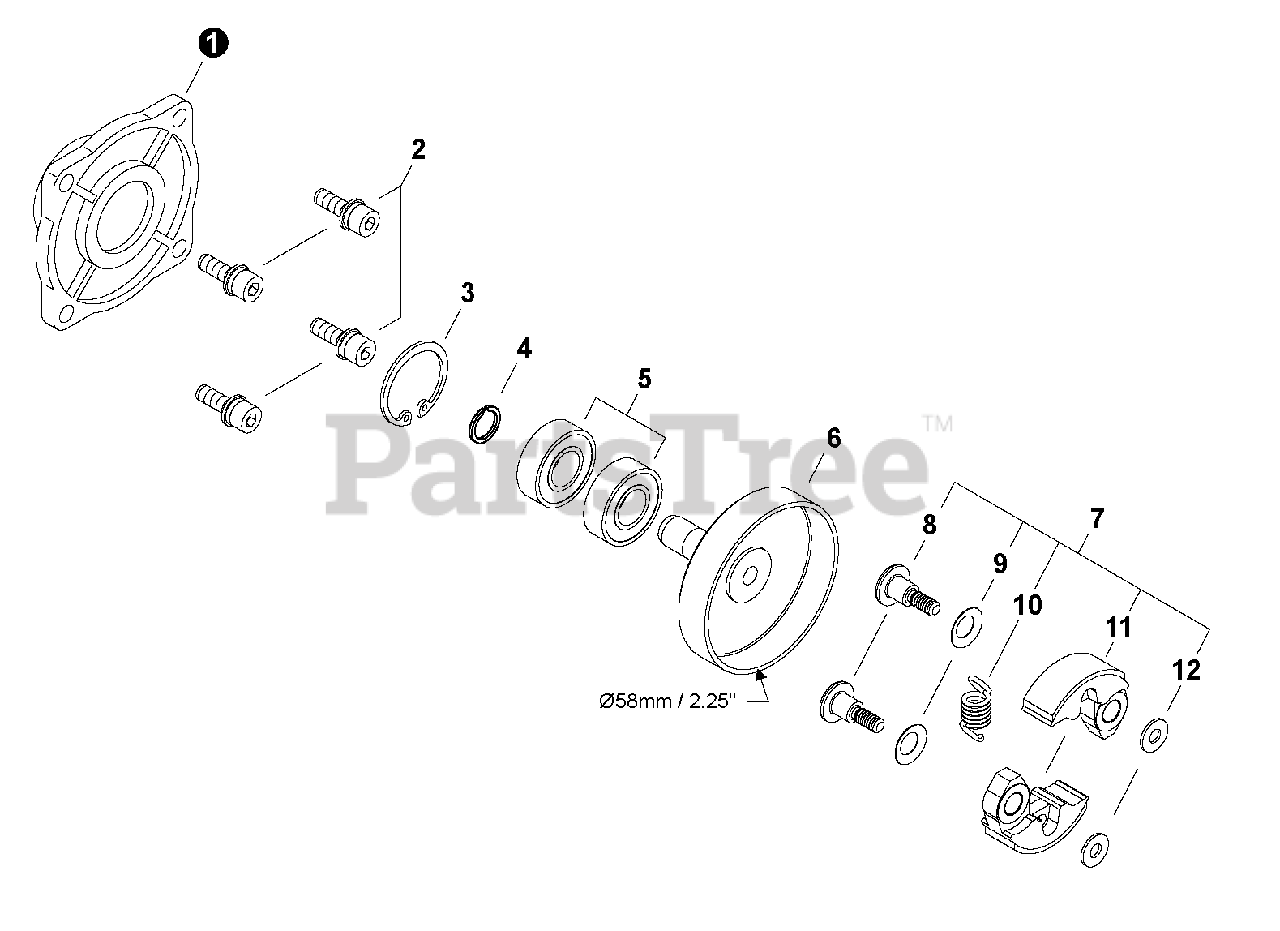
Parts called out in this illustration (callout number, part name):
1	Case, Clutch
2	Bolt M5x16
3	Ring, Snap dia.28
4	Ring, Snap dia.12
5	Bearing, Ball 6001 Ddu C3
6	Drum, Clutch
7	Clutch Assy
8	Bolt, Clutch
9	Washer, Spring
10	Spring, Clutch
11	Shoe, Clutch
12	Washer 6mm
